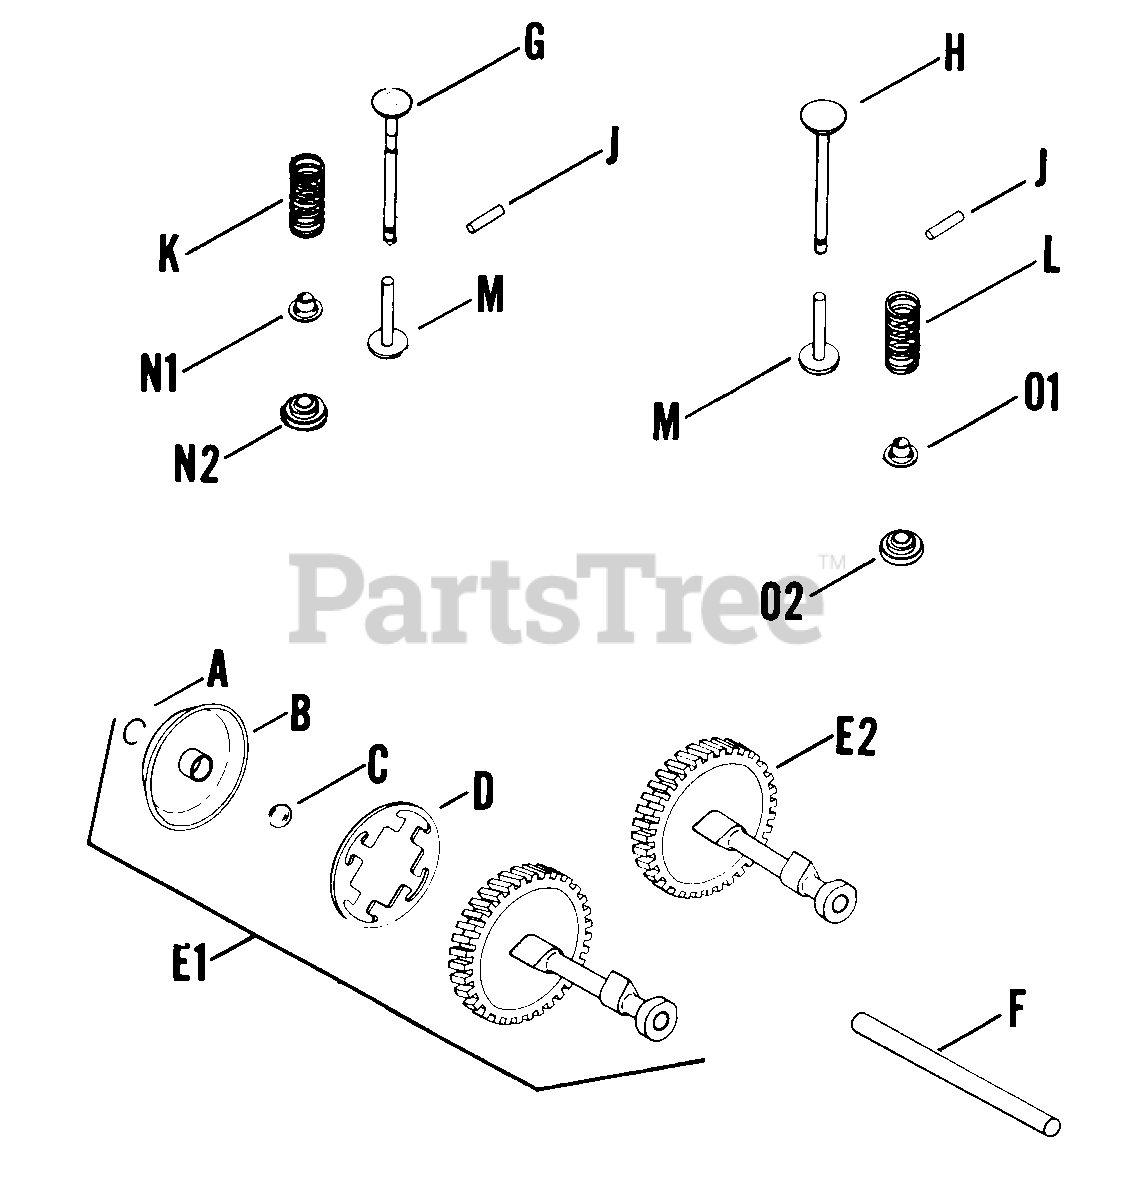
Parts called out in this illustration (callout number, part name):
A	RING - DISCONTINUED
E1	CAMSHAFT - DISCONTINUED
F	PIN - DISCONTINUED
H	VALVE - DISCONTINUED
J	PIN - (#DSC)
K	SPRING - DISCONTINUED
L	SPRING - DISCONTINUED
M	TAPPET - (#DSC)
N1	RETAINER - DISCONTINUED
O1	RETAINER - DISCONTINUED
